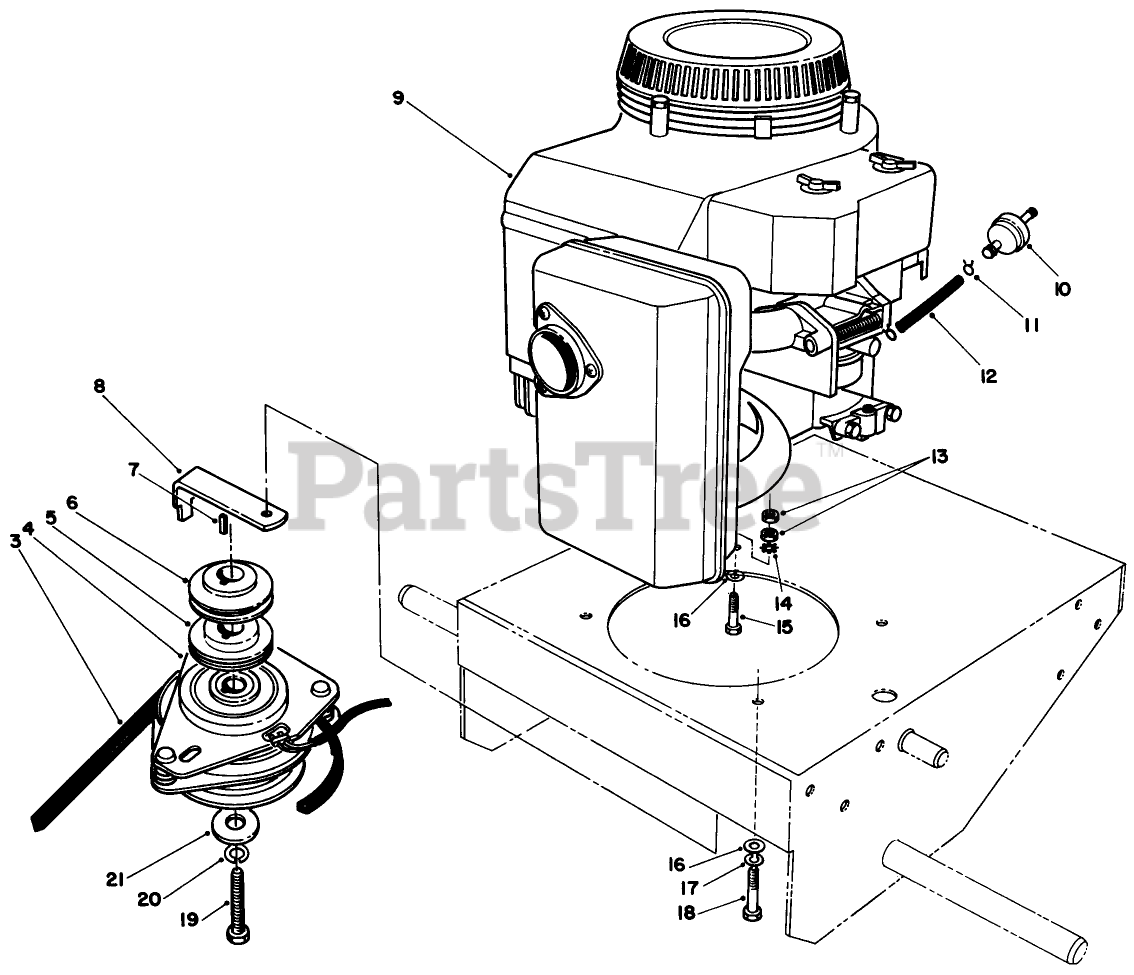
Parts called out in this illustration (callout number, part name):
3	V-BELT, DRIVE
5	SHEAVE-HALF, LOWER
6	SHEAVE-HALF, UPPER
7	KEY-SQUARE
10	FILTER-FUEL
11	CLAMP-HOSE
13	NUT-JAM
14	WASHER-LOCK
15	SCREW
16	WASHER-PLAIN
17	WASHER-LOCK
19	SCREW-CLUTCH
20	WASHER-LOCK
